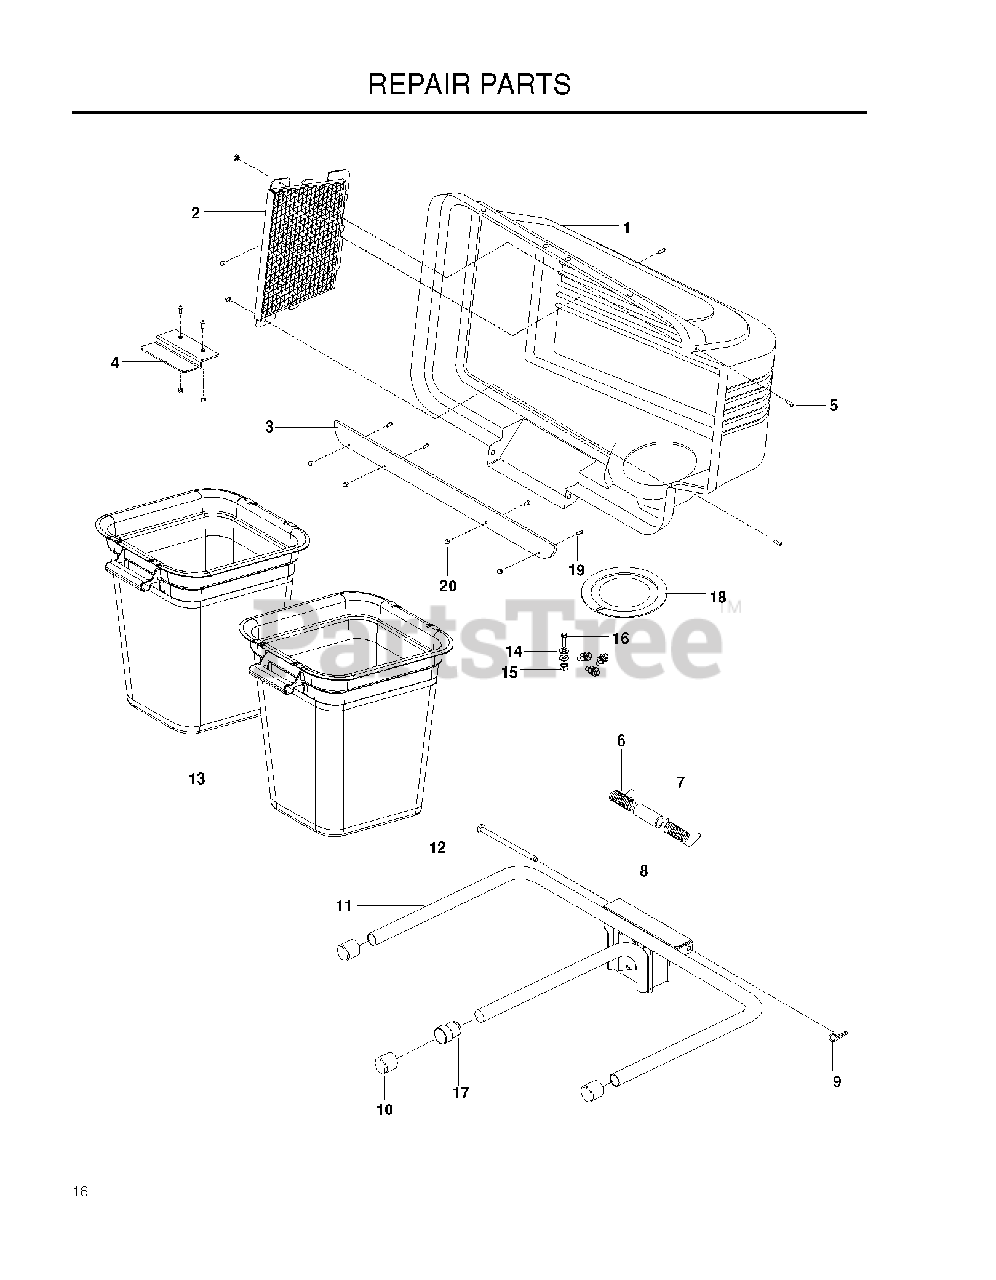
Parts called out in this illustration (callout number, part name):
1	HOOD ASM
2	COVER SCREEN
3	STRIP.REINFORCE.BAGGER.2BIN.BL
4	LATCH CER38
5	SCREW #10-24 X 5/8
6	SPRING COVER LH
7	SPRING COVER RH
8	SPACER.COVER.BAGGER
9	RETAINER SPRING
10	PLUG, TUBING END
11	FRAME.ASM.BAGGER.2BIN.QC42B
12	HINGE PIN
13	CONTAINER BAG, SOFT
14	WASHER #10
15	NUT 10-24 NYLOC
16	SCREW 10-24 X 3/4
17	SPACER PLUG, BAGGER
18	GASKET.COVER.BAGGER
19	SCREW
20	NUT 10-24 ACORN ZD
